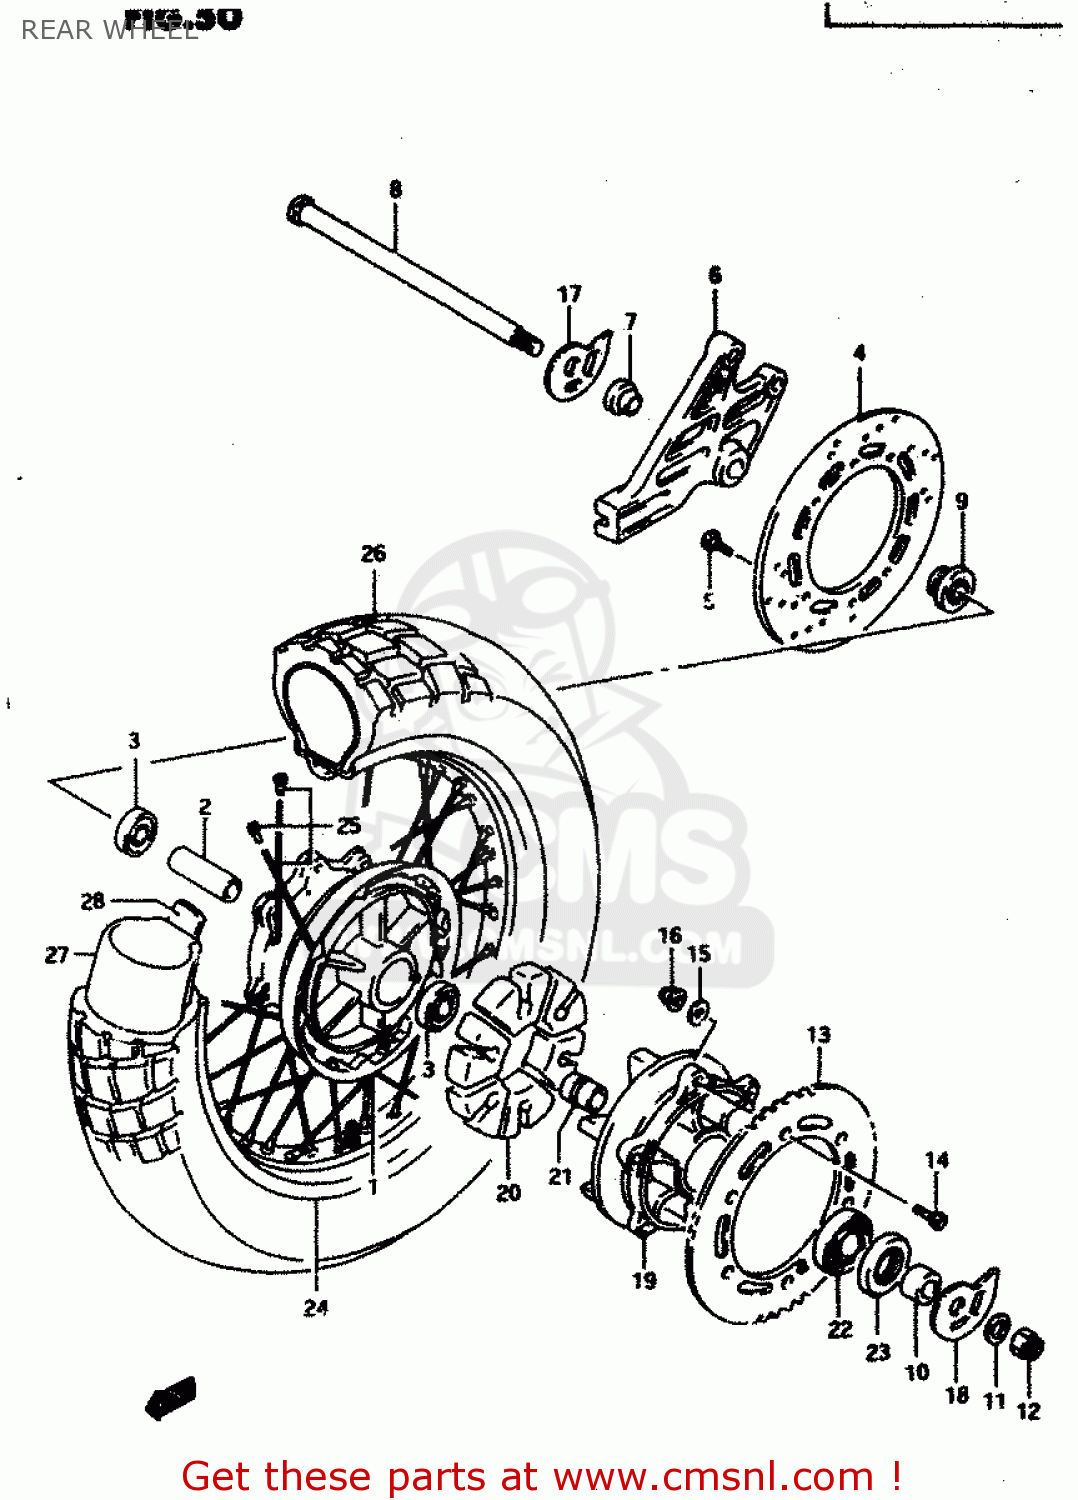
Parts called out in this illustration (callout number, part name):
1	HUB COMP,REAR WHEEL
2	SPACER(17.5X25X78)
3	BEARING
4	DISC,RR BRAKE
5	BOLT,BRAKE DISC
6	BRACKET,RR CALIPER
7	SPACER (17X21X10)
8	AXLE,REAR
9	SPACER,RR AXLE,L
10	SPACER(17X33X22.4)
11	WASHER (17X30X3.2)
12	NUT
13	SPROCKET,RR(NT:42)
14	BOLT(8X30.5)
15	WASHER
16	NUT
17	ADJUSTER,CHAIN,R
18	ADJUSTER,CHAIN,L
19	DRUM,REAR SPROCKET
20	ABSORBER,RR HUB SHOCK
21	RETAINER,RR SPROCKET DRUM
22	BEARING(25X62X17)
23	SEAL,OIL(33X62X7)
24	RIM,RR WHEEL(17XMT2.50)
25	SPOKE SET,RR
26	TIRE,REAR 120/90-17 64
27	TUBE ASSY,WHEEL INNER
28	PROTECTOR,WHL INR TUBE
